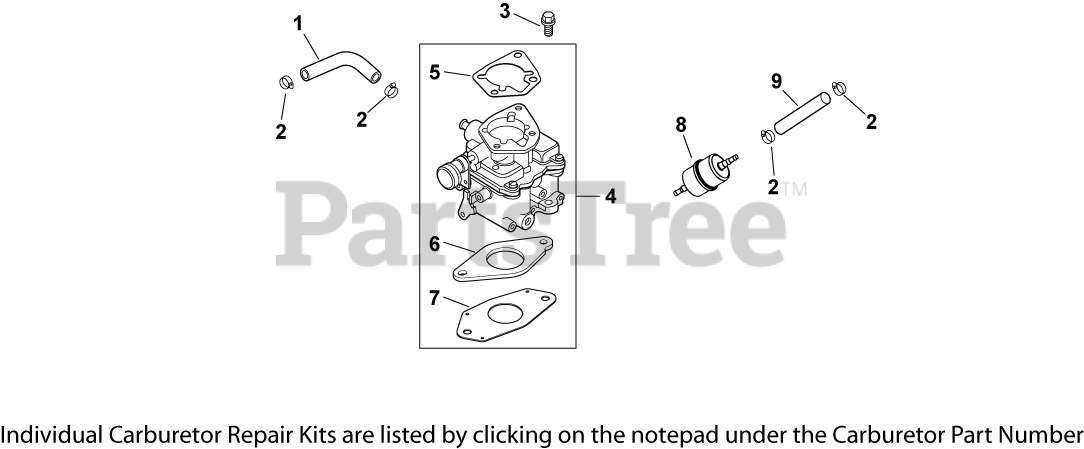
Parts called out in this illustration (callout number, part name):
1	LINE, FLEXIBLE FUEL 15 1/2"
2	CLAMP, HOSE (KM)-USE 25 237 31-S
3	SCREW, FLG M6X1.0X30
4	KIT, CARBURETOR W/GASKETS
5	GASKET, AIR CLEANER BASE
6	GASKET, CARBURETOR
7	GASKET, CARBURETOR
9	LINE, FUEL 11"
